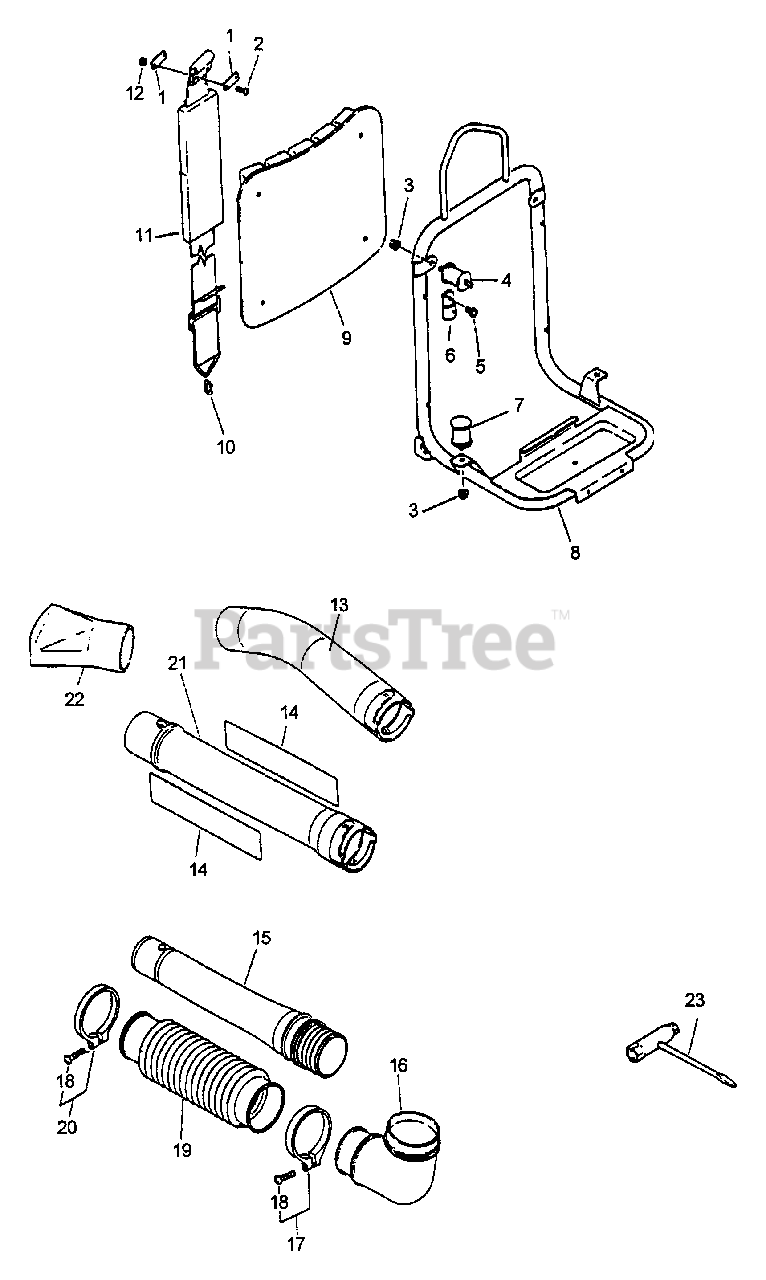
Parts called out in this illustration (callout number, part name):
2	SCREW - 5X10
3	NUT - 6 -- FLANGE
5	SCREW - 5X10
6	BRACKET, CUSHION
8	FRAME, BACKPACK
9	CUSHION, BACKPACK
10	RING, STRAP
11	BACKPACK STRAP ASSY
12	LOCKNUT - 5
13	TUBE, BLOWER - CURVED
14	LABEL - ECHO
15	TUBE, BLOWER - SWIVEL
16	TUBE, BLOWER - ELBOW
17	CLAMP KIT
18	SCREW - 5X30
19	TUBE, BLOWER - FLEXIBLE
20	CLAMP KIT
21	BLOWER TUBE KIT - STRAIGHT
22	NOZZLE - FAN HEAD
23	T-WRENCH - 10X19mm
